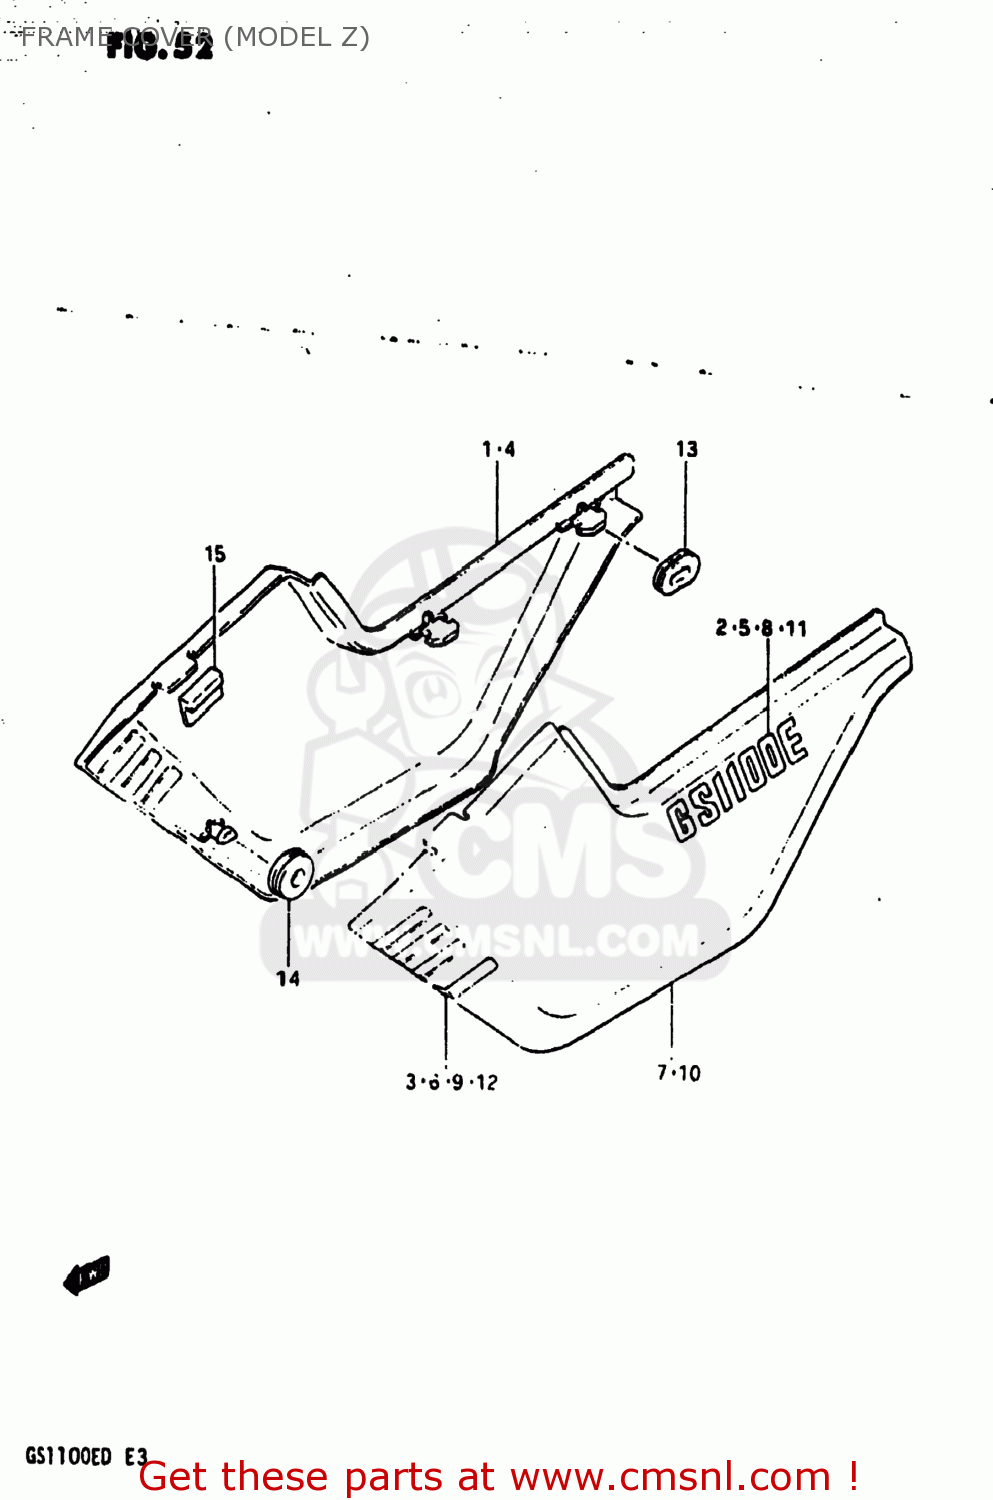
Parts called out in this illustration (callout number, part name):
1	COVER,FRAME,R
2	EMBLEM
3	LABEL, DENT
4	COVER,FRAME,RIGHT
5	EMBLEM
6	LABEL, DENT
7	COVER,FRAME,L
8	EMBLEM
9	EMBLEM,FRAME COVER,CENTER
10	COVER,FRAME,LEFT
11	EMBLEM
12	EMBLEM,FRAME COVER,CENTER
13	CUSHION
14	CUSHION
15	CUSHION,FRAME COVER
